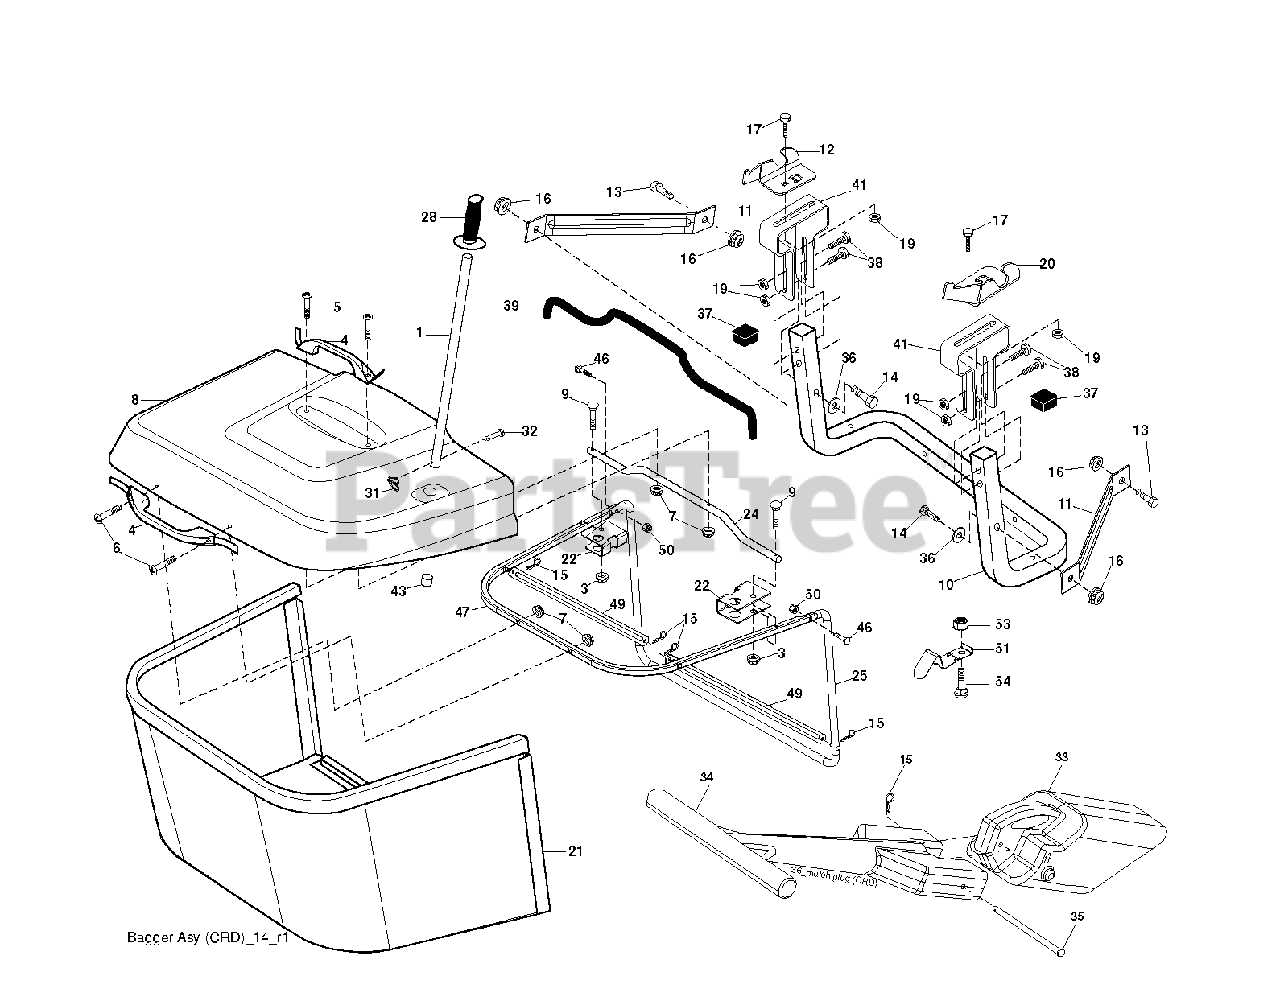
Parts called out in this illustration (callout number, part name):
1	TUBE HANDLE
3	NUT T
5	SCREW.PAN.HEAD
11	BRACKET
14	BOLT-HEX EAK
15	RETAINER-SPRNG RB
16	NUT LOCK FLG 3/8-16 UNC
17	BOLT
19	NUT LOCK HEX FLANGE 5/16-18
20	BRKT.PIVOT.RH.CRD
21	BAGGER.ASM.CRD.2007
22	BRACKET
24	TUBE
28	GRIP.HANDLE.BLACK
31	RETAINER CLIP
32	RIVET,DRILLED
33	MULCH PLUG, CTH150
35	PIN
38	BOLT.5/16-18X2.5
39	SEAL.BAGGER.CRD
41	BRKT, BAGGER
43	PLUG, TUBING END
46	BOLT.CARRIAGE.5/16-18
50	NUT.71038.31-18.HEX.NYLOCK
53	NUT
54	BOLT
